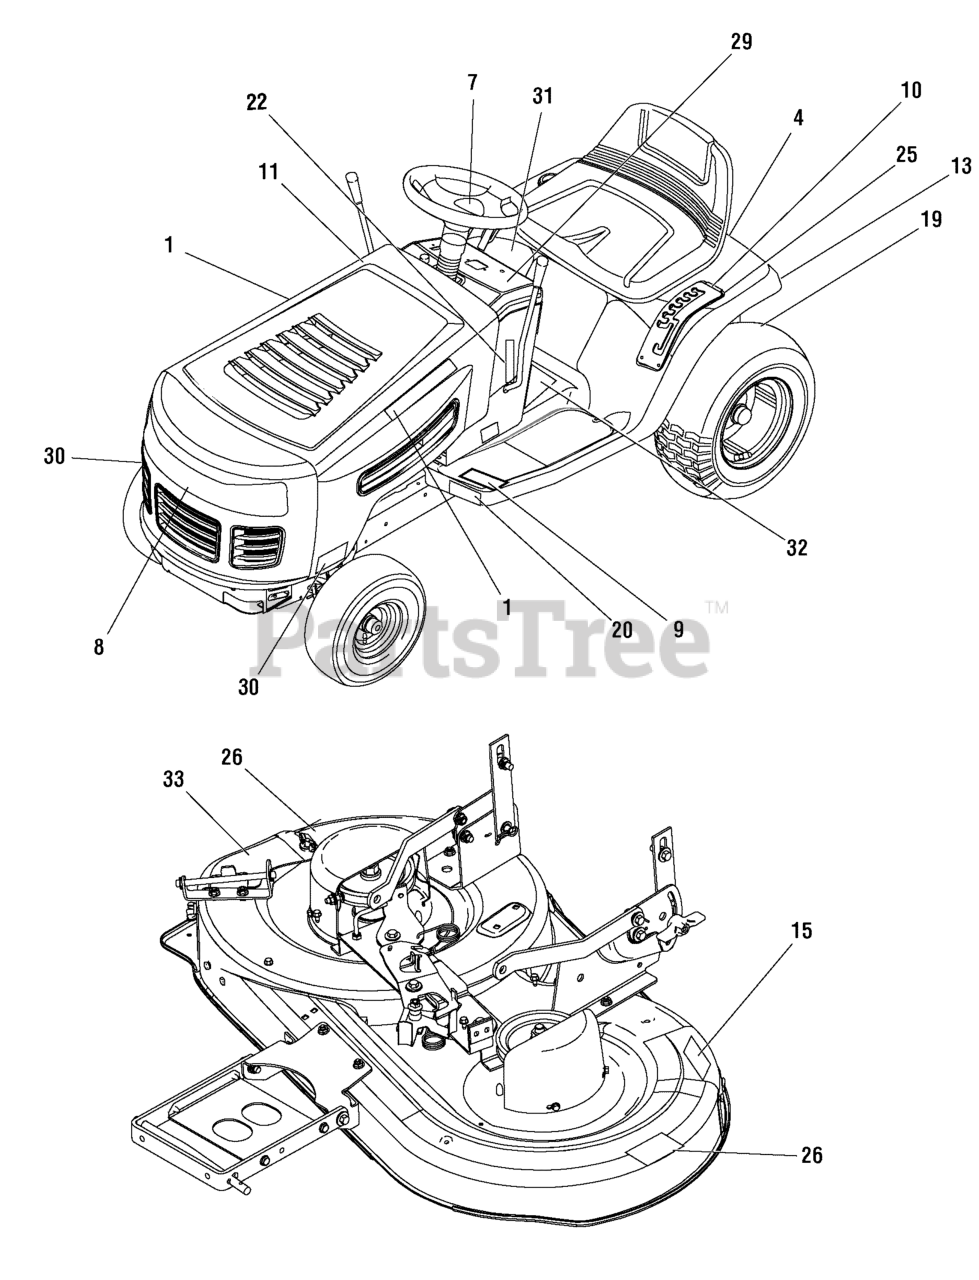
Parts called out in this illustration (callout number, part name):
1	DECAL, Logo, Side Hood
4	DECAL, Murray, Rear
7	DECAL, Steering Wheel
8	DECAL, Front Hood
9	DECAL, Belt/ Clutch
10	DECAL, Deck Level
11	DECAL, Cut Height, 7 Position
13	DECAL, Roll Release
15	DECAL, No Step
19	DECAL, Weight Limitation
20	DECAL, Drive Pedal
22	DECAL, Gas Gauge
25	DECAL, Deck Level
26	DECAL, Danger Do Not Operate w/o Deflector
29	DECAL, Dash / Symbols X-W Styles
30	DECAL, MT60
31	DECAL, 15.5HP I/C
32	DECAL, Umber
33	DECAL, Deck Width, 96 cm, 38 in
